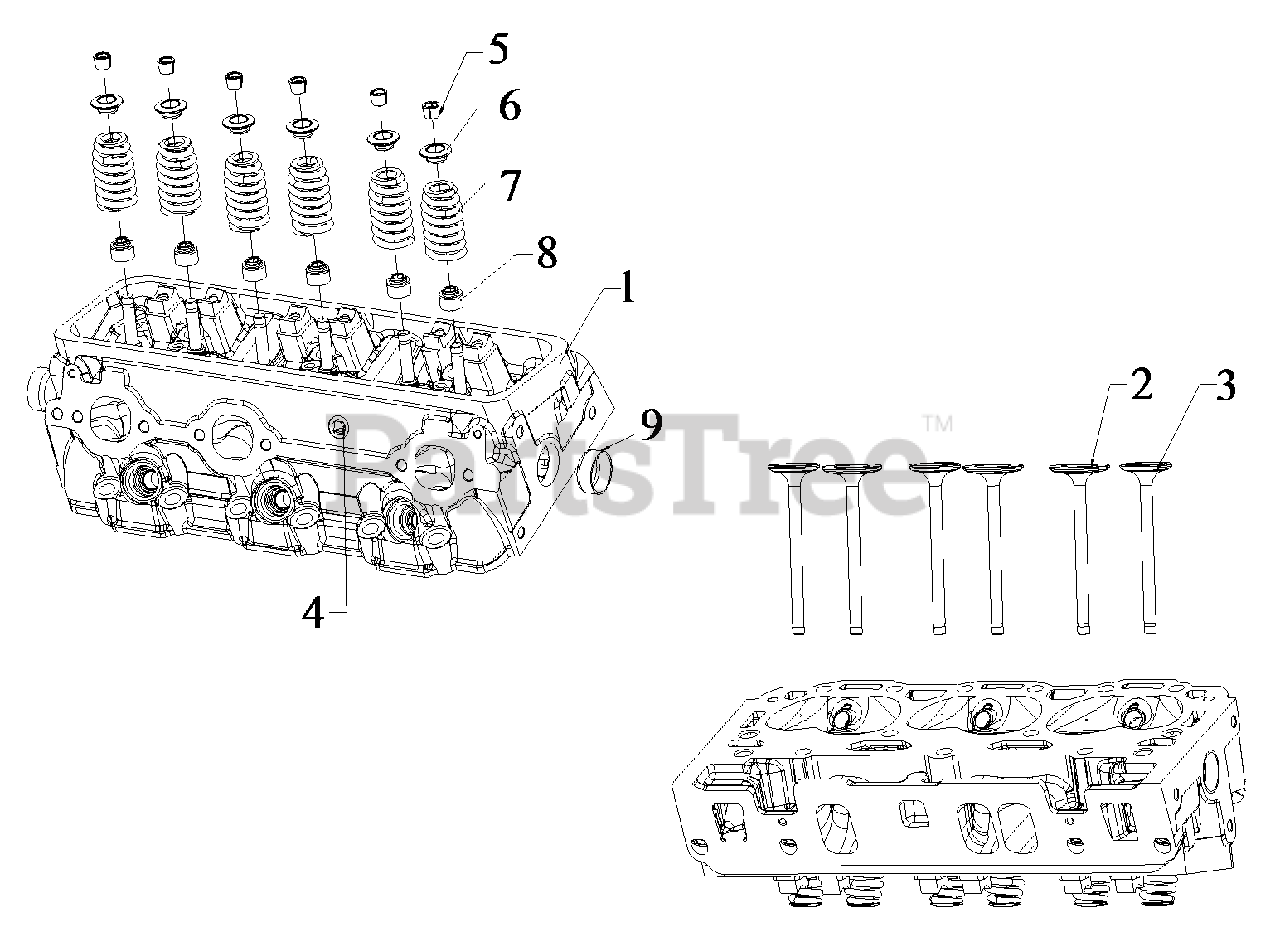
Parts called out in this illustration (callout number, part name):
1	CYLINDER HEAD
2	VALVE, INTAKE
3	VALVE, EXHAUST
4	PLUG
5	KEY
6	RETAINER
7	VALVE SPRING
8	SEAL, VALVE STEM
